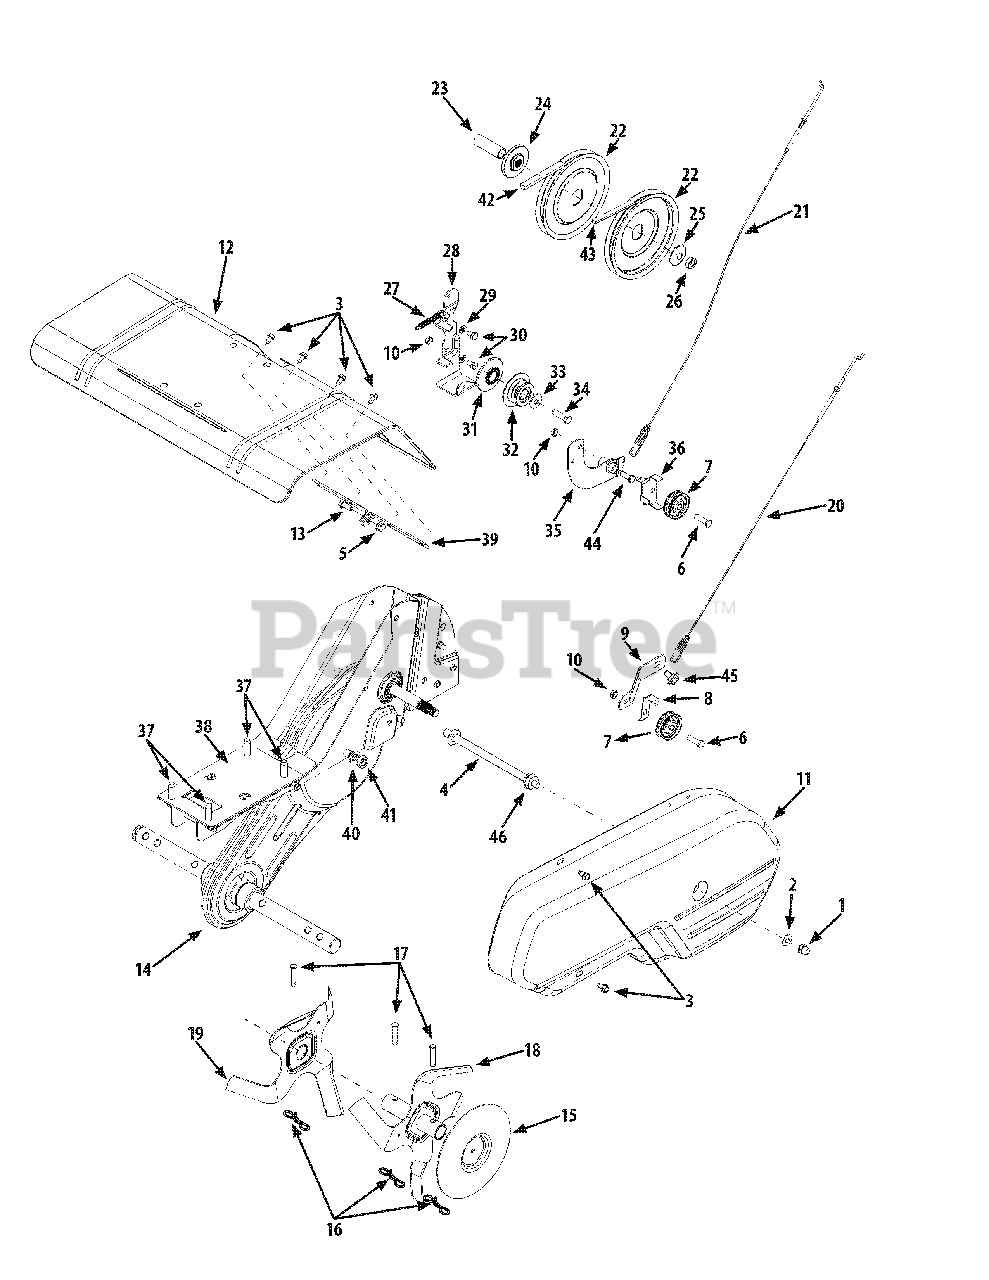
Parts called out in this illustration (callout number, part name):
1	Hex L-Stop Nut, 1/4-28
2	Flat Washer, 266" x .625"
3	Hex Washer TT-Tap Screw, 1/4-20 x .5"
4	Belt Cover Bolt
5	Hex Flange Top L-Nut, 5/16-18
6	Hex Head Screw, 3/8-16 x 1.25"
7	Flat Idler Pulley, 2.12"
8	Idler Belt Keeper
9	Idler Bracket
10	Hex Center Jam Nut, 3/8-16
11	Belt Cover
12	Tine Shield
13	Hex Head Cap Screw, 5/16-18 x .75"
14	Chain Case Assembly Complete
15	Outer Disc Plate Assembly
16	Cotter Pin, Bow Tie
17	Clevis Pin
18	Outer Tine Assembly, Left
18	Outer Tine Assembly, Right
19	Inner Tine Assembly, Left
19	Inner Tine Assembly, Right
20	Forward Clutch Cable
21	Reverse Clutch Cable
22	Flat Pulley, 6"
23	Spacer, .64" x 2.4"
24	Pulley Mounting Adapter
25	Bell Washer, 525" x 1.5"
26	Hex Jam Nut, 1/2-20
27	Return Spring
28	Reverse Bracket
29	Lock Washer, 5/16
30	Hex Bolt, 5/16-24 x .625"
31	Engine Inner Pulley
32	Reverse Engine Pulley
33	Bell Washer, .396" x 1/14"
34	Hex Bolt, 3/8-24 x 1.00"
35	Reverse Arm Assembly
36	Reverse Belt Keeper
37	Hex L-Washer TT-Tap, 3/8-16 x 1.25"
38	Engine Plate
39	Tine Shield Bracket
40	L-Washer, 7/16"
41	Hex Nut, 7/16-20
42	Forward Drive Belt, 1/2 x 41.9"
43	Reverse Drive Belt, 3/8 x 45.68"
44	Shoulder Screw, .498 x 1.445
45	Shoulder Screw, .560 x.165
46	Flangelock Nut, 5/16 - 18
